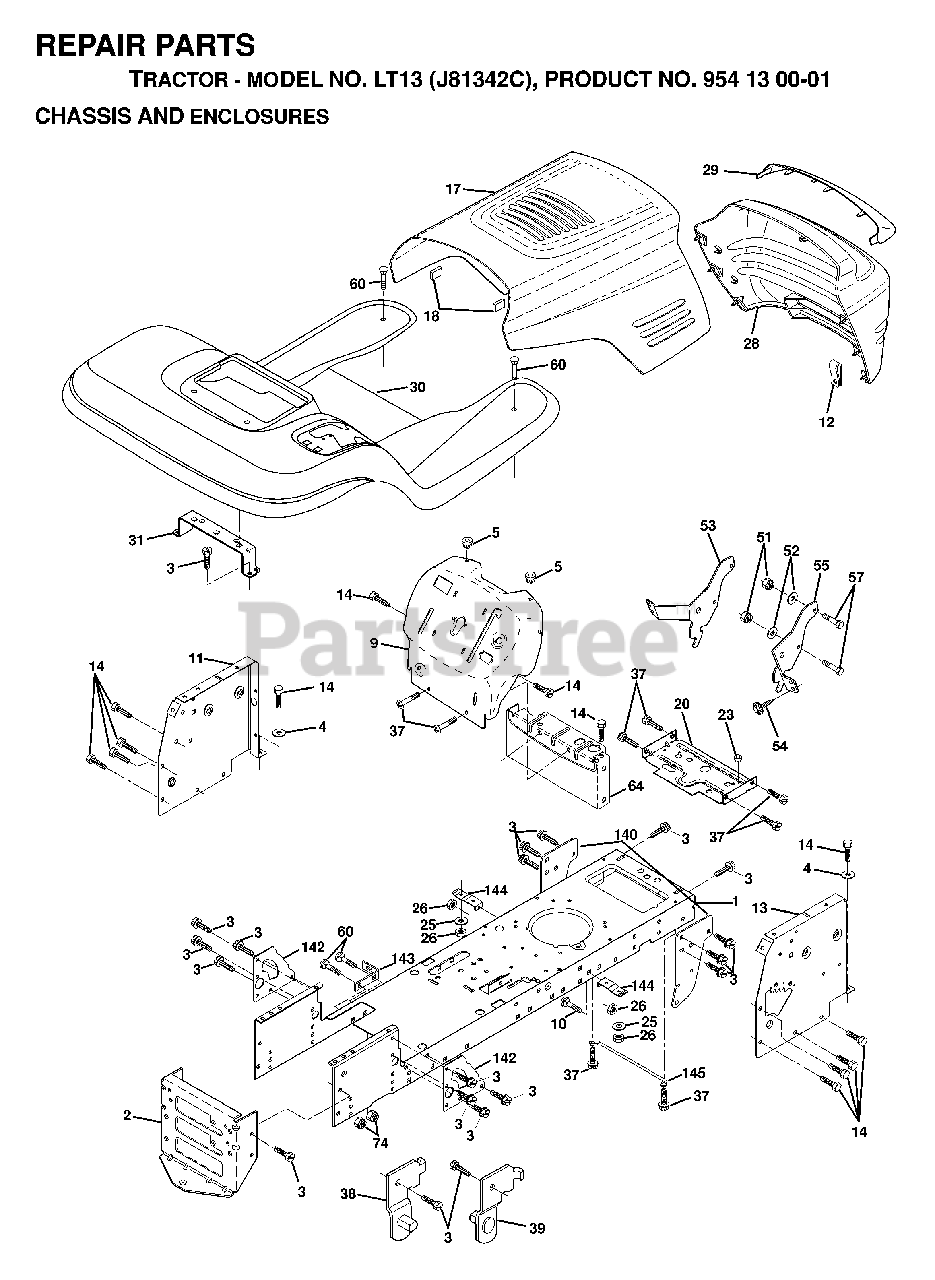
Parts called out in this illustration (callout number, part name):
2	STRETCH DRAWBAR
3	SCREW
5	BUMPER.RUBBER.HOOD
10	BOLT D
11	PANEL DASH LH
13	PANEL DASH RH
18	BUMPER HOOD T
20	PLATE MTG
23	GROMMET T
25	WASHER
26	NUT
38	BRACKET LH PIVOT
39	BRACKET RH PIVOT
51	LOCKNUT
57	BOLT
64	DASH LOWER
74	LOCKNUT
140	BRACKET SUSPENSION FRONT
142	PLATE REINFORCEMENT
143	BRACKET, SWAY BAR
144	BRACKET FOOTREST
145	ROD PIVOT CHASSIS/HOOD
